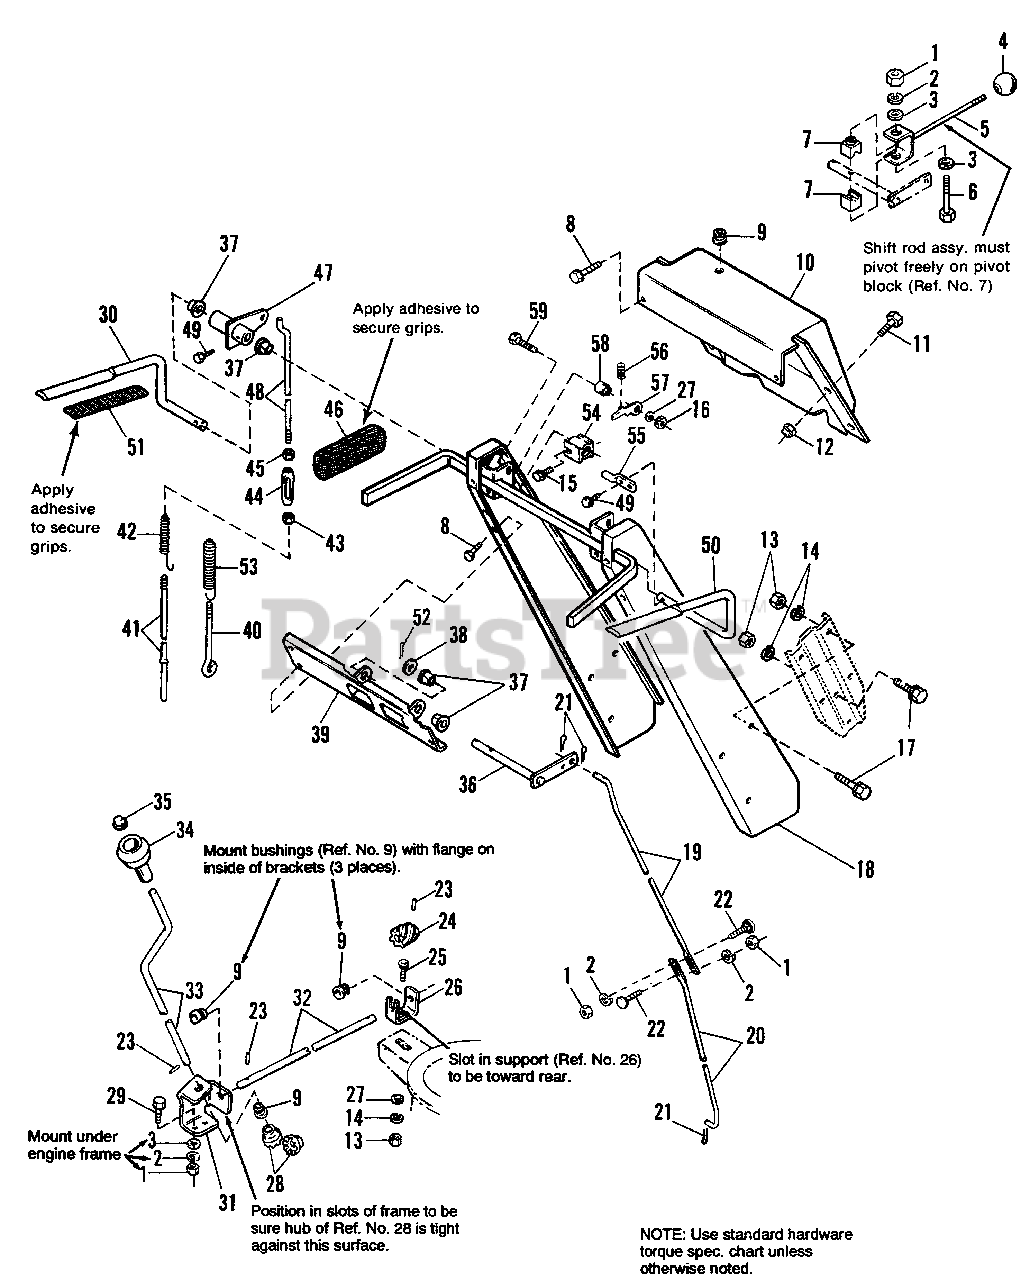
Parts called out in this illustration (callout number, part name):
1	NUT, Hex, 1/4-20
2	LOCKWASHER, 1/4
3	WASHER, Flat, 9/32
5	SHIFT ROD ASSY
6	CAPSCREW, Hex Hd., 1/4-20 x 2-1/4
7	BLOCK, Pivot
8	SCREW, Taptite, 1/4-20 x 1/2
9	BUSHING, Plastic
10	DASH, Handle
11	CAPSCREW, Washer Hd., 1/4-20 x 3/4
12	NUT, Nylon Lock, 1/4-20
13	NUT, Hex, 5/16-18
14	LOCKWASHER
15	SCREW, Taptite, #10-24 x 1
16	NUT, Hex Lock, 5/16-18
17	CAPSCREW, Whizlock 5/16-18 x 3/4
18	HANDLE ASSY.
19	ROD, Shift, Upper
20	ROD, Shift Lower
21	PIN Cotter
22	BOLT, Carriage, 1/4-20 x 3/4
23	PIN, Roll, 1/8 x 3/4
24	WORM, Chute
25	BOLT, Carriage, 5/16-18 x 3/4
26	SUPPORT, Worm
27	WASHER, Flat, 11/32
28	GEAR, Universal
29	CAPSCREW, Hex Hd., 1/4-20 x 3/4
30	HANDLE, Clutch, L.H.
31	SUPPORT, Universal Gear
32	ROD, Chute Worm
33	ROD, Chute Control
34	KNOB, Spinner
35	PALNUT
36	PIVOT ROD ASSY.
37	BUSHING, Plastic
38	WASHER
39	BRACKET, Shift Control
40	ROD, Clutch-Lower, Auger
41	ROD, Clutch-Lower, Traction
43	NUT, Hex, #10-24, R.H.
45	NUT, Hex, #10-24, L.H.
46	GRIP, Handle Bar
47	CLUTCH LEVER ASSY.
48	ROD, Clutch-Upper
49	SCREW, Taptite, #10-24 x 1
50	HANDLE, Clutch R.H.
51	GRIP, Clutch
52	PIN, Cotter, 1/8 x 1
53	SPRING, Extension
54	GUIDE, Control
55	ROD, Control
56	SPRING
57	LATCH, Control
58	SPACER, Special
59	CAPSCREW, Hex Hd., 5/16-18 x 1-1/2
